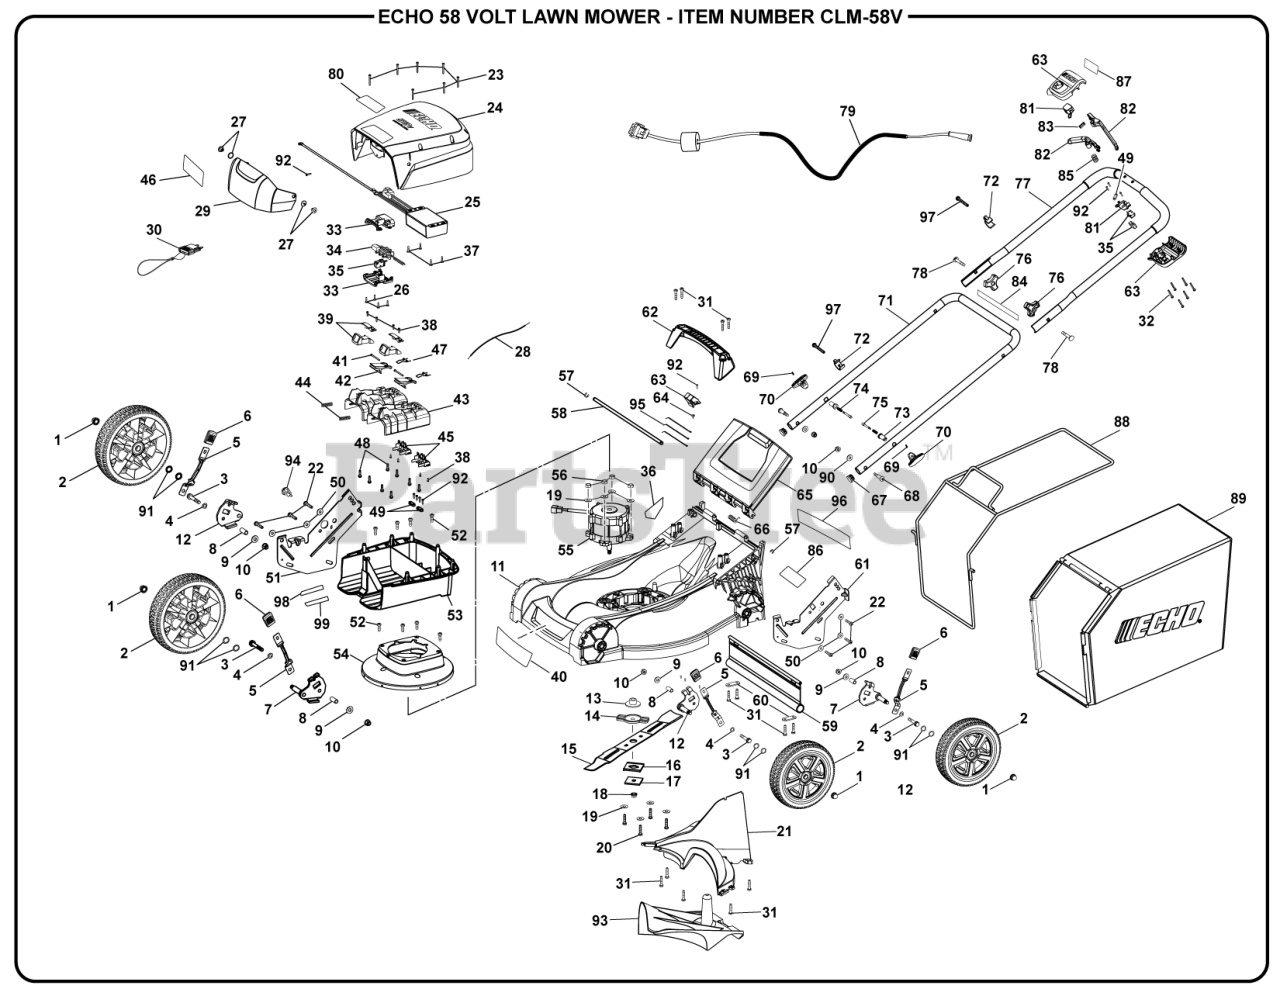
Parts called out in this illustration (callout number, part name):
1	Cap Nut
2	Wheel Assembly
3	Bolt (M8 x 50 mm)
4	Spring Washer (OD15 x ID8.4 x 0.8t)
5	Cutting Height Adjustment Lever
6	Height Adjustment Knob
7	Adjustment Axle Plate (Right Front and Left Rear)
8	Front Collar (Deck)
9	Washer (OD20.5 x ID8.5 x 2t)
10	Flange Nut (M8)
11	Deck (Inc. Labels)
12	Adjustment Axle Plate (Right Rear and Left Front)
13	Bushing (Motor Axle)
14	Blade Holder
16	Spacer (Plastic)
17	Blade Retainer
18	Hex Nut (M10)
19	Washer (OD15 x ID6.2 x .08t)
20	Screw (M6 x 26 mm)
21	Discharge Baffle
22	Screw (1/4-15 x 17 mm, T30 Torx Pan Hd.)
23	Screw (M4 x 18 mm Torx Hd.)
24	Motor Cover (Upper, Includes Labels)
25	Control Panel Assembly
26	Screw (M3.5 x 12 mm, Pan Hd.)
27	Rivet Assembly (Male and Female Set)
28	Lead Wire (185 mm, Yellow)
29	Battery Cover (Upper Lid, Includes Labels)
30	Start Key Assembly
31	Screw (1/4-15 x 1-1/4 in., T30 Torx Pan Hd.)
32	Screw (M4 x 30 mm)
33	Key Housing Assembly
34	Pin Socket Assembly
35	Switch (On/Off)
36	No Hands or Feet Label/CPSC Label
37	Screw (M4 x 16 mm)
38	Screw (M3 x 12 mm, Pan Hd.)
39	Battery Release Button and Retainer Assembly
40	Front Cover Label
41	Battery Latch
42	Battery Release Latch
43	Battery Carriage
44	Compression Spring
45	Battery Contact Assembly
46	Logo Label
47	Torsion Spring
48	Screw (M5 x 17.5 mm, T20 Torx Pan Hd.)
49	Cord Clamp
50	Washer (1/4 in.)
51	Handle Adjustment Mount (Right)
52	Screw (1/4-15 x 3/4 in., T30 Torx Pan Hd.)
53	Motor Cover (Center, Includes Labels)
54	Motor Cover (Lower)
56	Hex Nut (M6)
58	Axle (Rear Door)
59	REAR GUARD
60	Bracket (Rear Guard)
61	Handle Adjustment Mount (Left)
62	Deck Handle
63	Switch Cover and Housing Assembly (Includes Labels)
64	Screw (M3 x 12 mm, Pan Hd.)
65	Rear Door
66	Compression Spring (Rear Door)
67	End Cap
68	Screw (M8.0 x 18 mm, T40 Torx Hd.)
69	Spring Pin (11 mm)
70	Spring Pin Adjustment Knob
71	LOWER HANDLE
71	Lower Handle (Serial Number After and Including EU18152N020001, 4.11.18)
72	Cord Clamp
72	Cord Clamp (Serial Number After and Including EU18152N020001, 4.11.18)
73	Spring Pin (Housing)
74	Compression Spring
75	Detent Pin
76	Wing Nut w/Insert
77	Upper Handle Assembly
77	Upper Handle Assembly (Serial Number After and Including EU18152N020001, 4.11.18)
78	Screw (M8 x 57 mm)
79	Wire Assembly
79	Wire Assembly (Serial Number After and Including EU18152N020001, 4.11.18)
80	Start Key Warning Label
81	Spring Holder and Button Assembly
82	Trigger Assembly
84	"Power-Adapt" Label
85	Compression Spring
86A	Data Label
86B	Data Label
87	Quick Start Label
88	Frame (Grass Bag)
89	Grass Bag Assembly
90	Washer (ID8.5 x OD20.5 x 3t)
91	Wavy Washer (ID13.7 x OD19.2)
92	Screw (M4 x 13.5 mm, T15 Torx Pan Hd.)
93	Mulching Plug
94	Switch (Serial Number Before EU18131, 3.26.18)
95	Cable Tie
96	Warning Icon Label
97	Screw (M3 x 20 mm)
98	Wet Conditions Warning Label (ENG/FR)
99	Wet Conditions Warning Label (SP)
